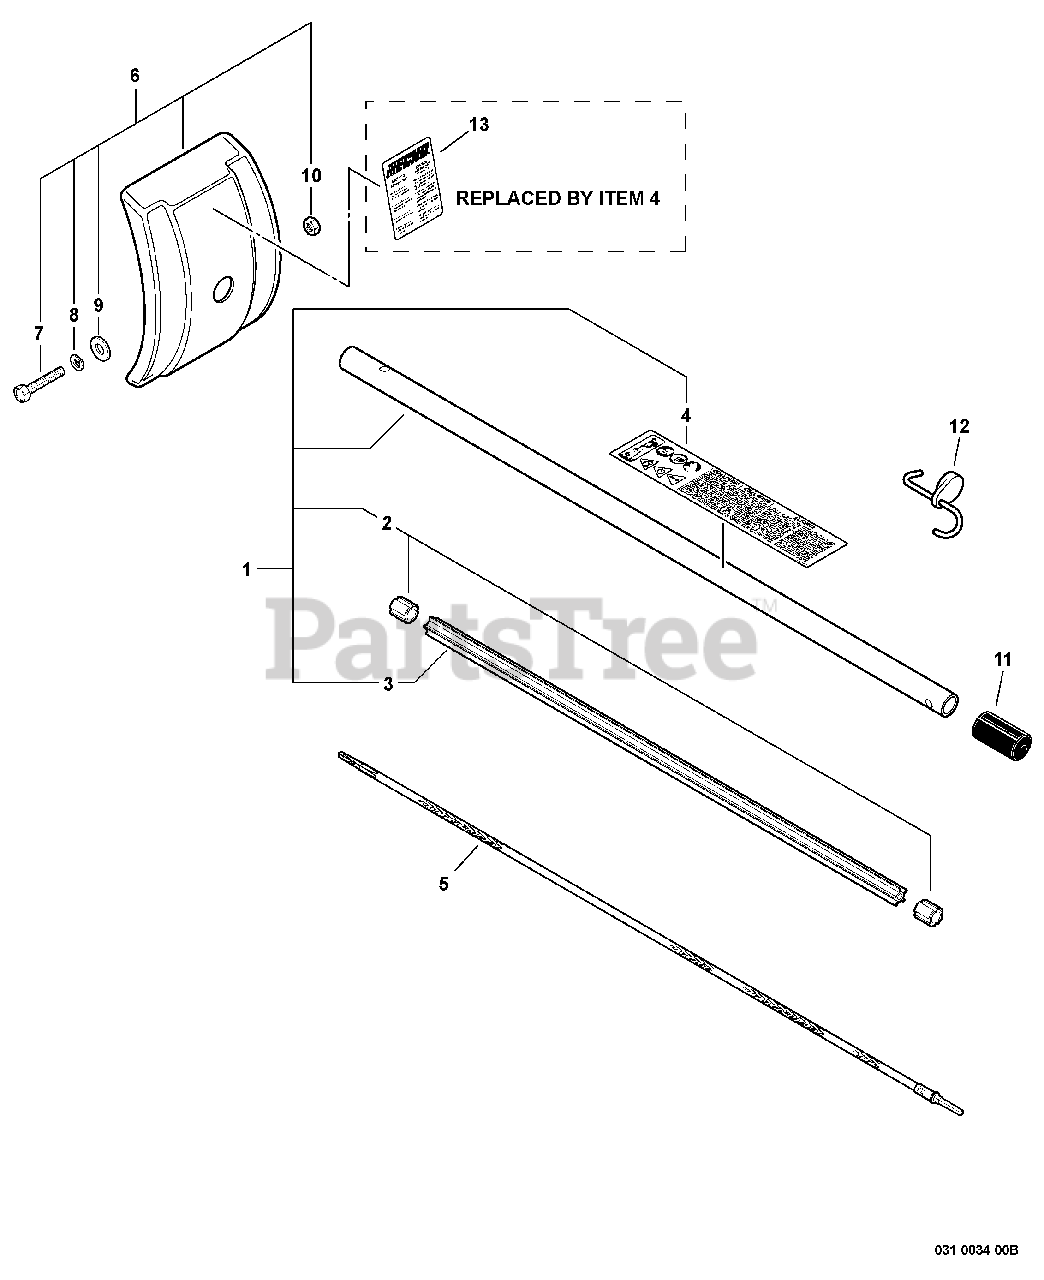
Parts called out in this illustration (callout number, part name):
1	MAIN PIPE ASSY
3	LINER - FLEXIBLE
4	LABEL, CAUTION
5	DRIVESHAFT - FLEXIBLE
6	DEBRIS SHIELD KIT
7	BOLT 6×20
8	WASHER, SPRING 6
9	WASHER 6.5×11.5×0.8
10	NUT, HEX M6
11	CAP, MAIN PIPE
12	HANGER, ATTACHMENT
13	LABEL - CAUTION
